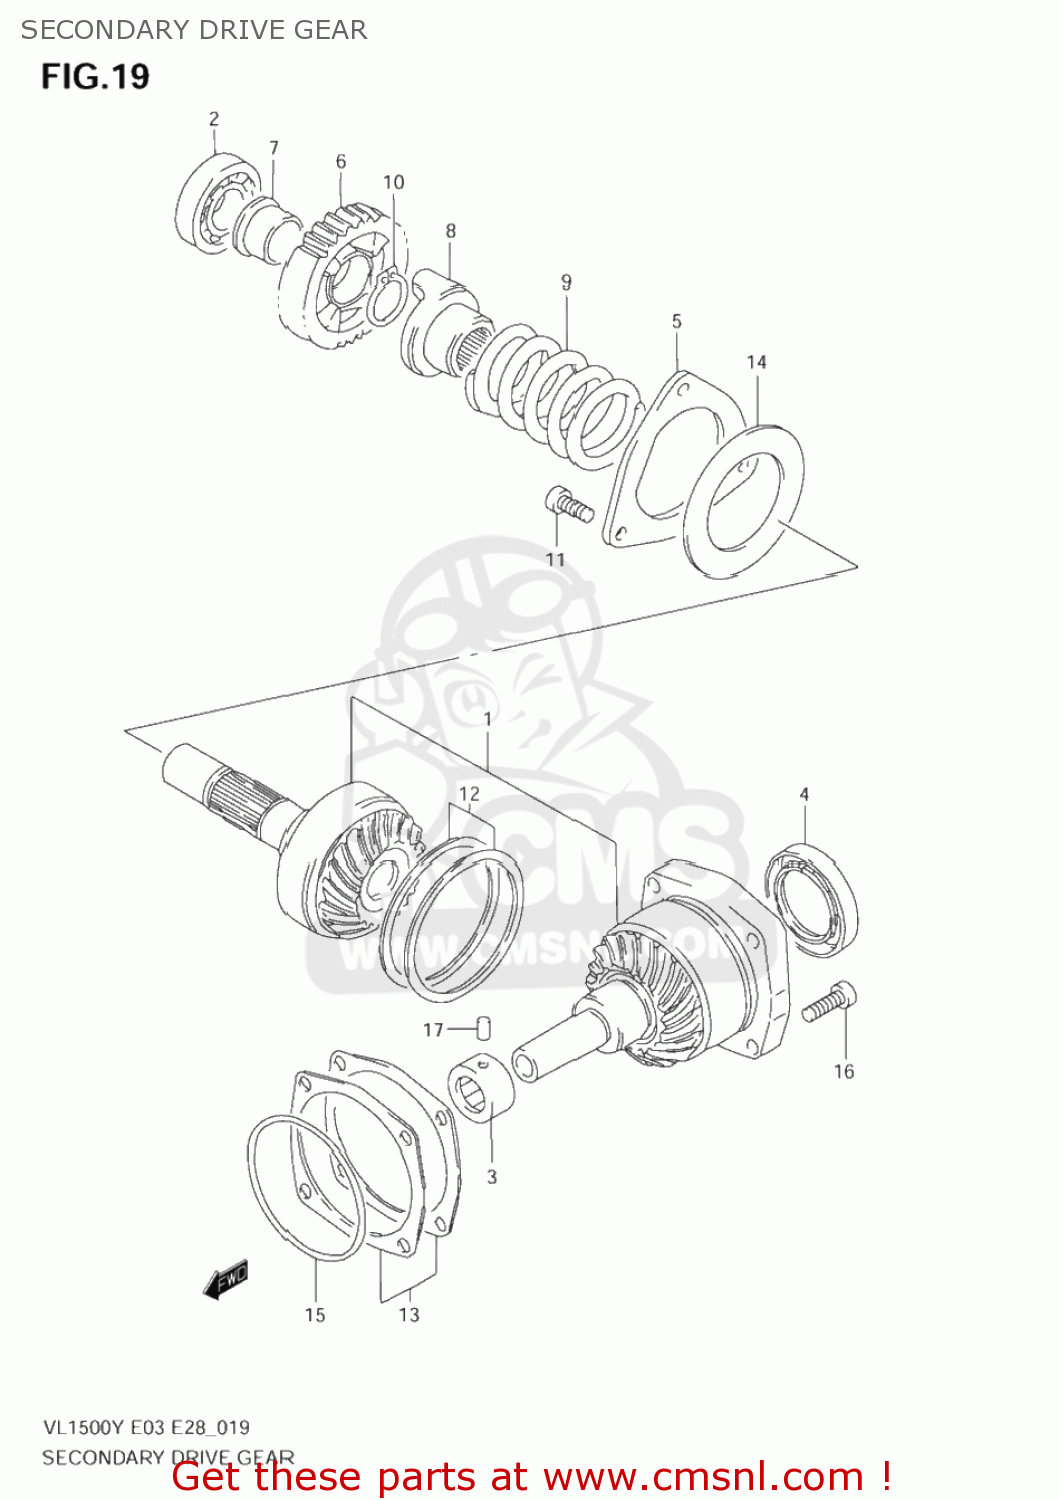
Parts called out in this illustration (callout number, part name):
1	GEAR & HOUSING SET,SECONDARY
2	BEARING(25X62X17)
3	BEARING(20X34X16)
4	SEAL,OIL(44X68X8)
5	STOPPER,SEC DRIVE BEARING
6	GEAR,OVER DRIVING DRIVEN
7	BUSHING,OD DRIVEN GEAR
8	DOG,OUTPUT CAM
9	SPRING
10	CIRCLIP
11	BOLT
12	SHIM SET,SEC DRIVE
13	SHIM SET,SEC DRIVEN
14	WASHER(57X90X3)
15	O RING(D:3.7,ID:76.5)
16	BOLT
17	PIN
